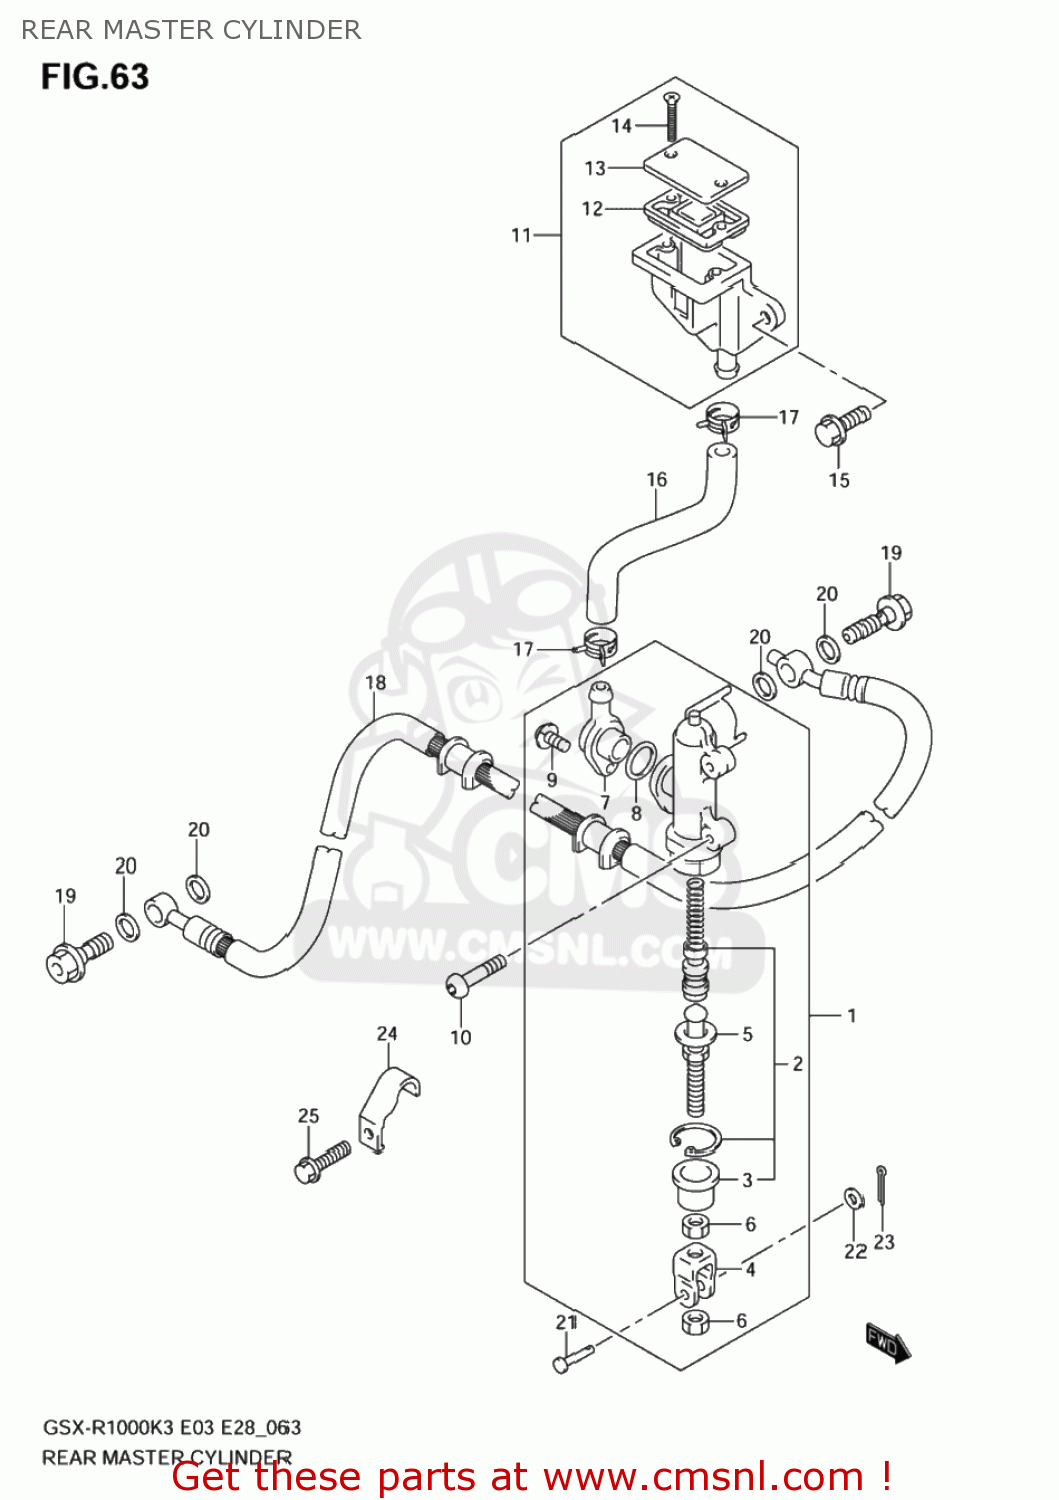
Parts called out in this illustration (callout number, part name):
1	CYLINDER ASSY,RR MASTER
2	PISTON/CUP SET
3	BOOT
4	YOKE
5	ROD,PUSH
6	NUT
7	CONNECTOR
8	O RING
9	SCREW
10	SCREW(6X20)
11	TANK ASSY,RR RESERVOIR
12	DIAPHRAGM
13	CAP
14	SCREW
15	BOLT(6X12)
16	HOSE,RR RESERVOIR TANK
17	CLIP
18	HOSE,RR BRAKE
19	BOLT UNION
20	WASHER(10X15X1.5)
21	PIN
22	WASHER
23	PIN
24	CLAMP,RR BRAKE HOSE
25	BOLT(6X20)
